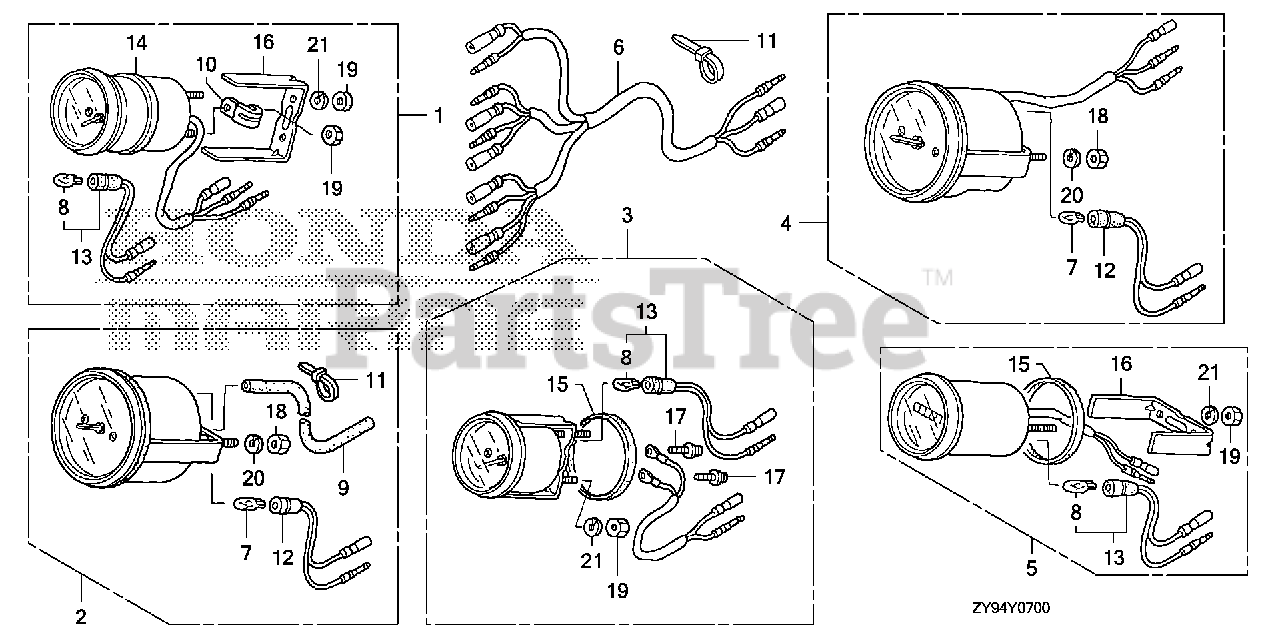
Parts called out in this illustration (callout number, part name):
1	METER KIT, TRIM
1	METER KIT, TRIM (B)
2	SPEEDOMETER KIT
2	SPEEDOMETER KIT (B)
3	METER KIT, VOLT
3	METER KIT, VOLT (B)
4	METER KIT, TACHO
4	METER KIT, TACHO (B)
5	METER KIT, HOUR (NA USE ALT:39700-ZW5-000ZA)
5	METER KIT, HOUR (B) (NA USE ALT:39700-ZW5-000ZA)
6	HARNESS ASSY., METER (B)
7	BULB, WEDGE BASE (T10) (12V 1.7W) (STANLEY)
8	BULB, WEDGE BASE (12V 1.7W)
9	TUBE, SPEED METER (4X7X8000)
10	CLAMP
11	BAND, SELF-LOCK
12	SOCKET
13	SOCKET
14	GASKET
15	GASKET
16	BRACKET
17	SCREW-WASHER (3X22)
18	NUT, HEX. (5MM)
19	NUT, HEX. (4MM)
20	WASHER, SPRING (5MM)
21	WASHER, SPRING (4MM)
